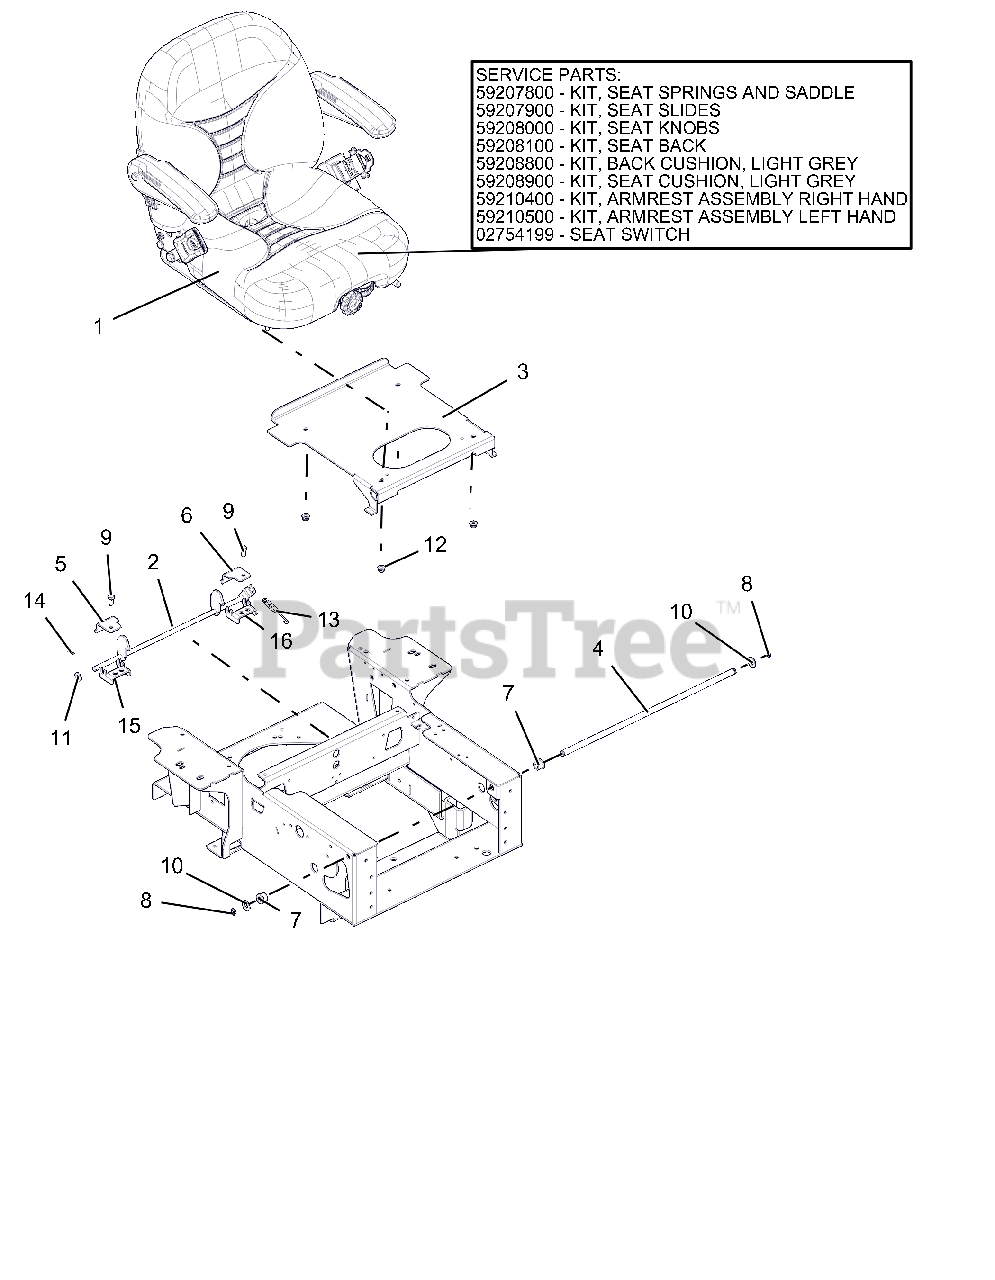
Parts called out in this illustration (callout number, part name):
1	SEAT, SUSPENSION W/SEAT BELT, LT GRAY
1	KIT, SEAT SPRINGS AND SADDLE
1	KIT, SEAT SLIDES
1	KIT, SEAT KNOBS
1	KIT, SEAT BACK
1	KIT, BACK CUSHION, LIGHT GREY
1	KIT, SEAT CUSHION, LIGHT GREY
1	KIT ARMREST ASSEMBLY RIGHT HAND
1	KIT ARMREST ASSEMBLY LEFT HAND
1	SEAT SWITCH
2	WLDMT, PRO-TURN SEAT LATCH-BLACK
3	WLDMT, PRO-TURN 100 SEAT PLATE - BLK
4	SHAFT, PT/PT100 SEAT PIVOT
5	MOUNT, PT/PT100 RH TOP SEAT LATCH-BLACK
6	MOUNT, PT/PT100 LH TOP SEAT LATCH-BLACK
7	BSHG, SHLDR EP .358-16X.30 HEX YZ
8	RG-RTNG-EXT .500x.050
9	BLT-HEX .31-18X.75 GR5 YWZC
10	WSHR-FL-STL .531X1.000X.063 YWZC
11	WSHR-FL-STL.406X.812X.065 YWZ
12	NUT-LK-NYL-FLG .31-18 YWZC
13	SPRG, EXTENSION
14	@PIN-CTR .09X.75 EXTPRSQCT YWZ
15	WLDMT, PT/PT100 RH SEAT LATCH MOUNT-BLACK
16	WLDMT, PT/PT100 LH SEAT LATCH MOUNT-BLACK
17	MOUNT, PT100 SEAT LATCH BOTTOM
